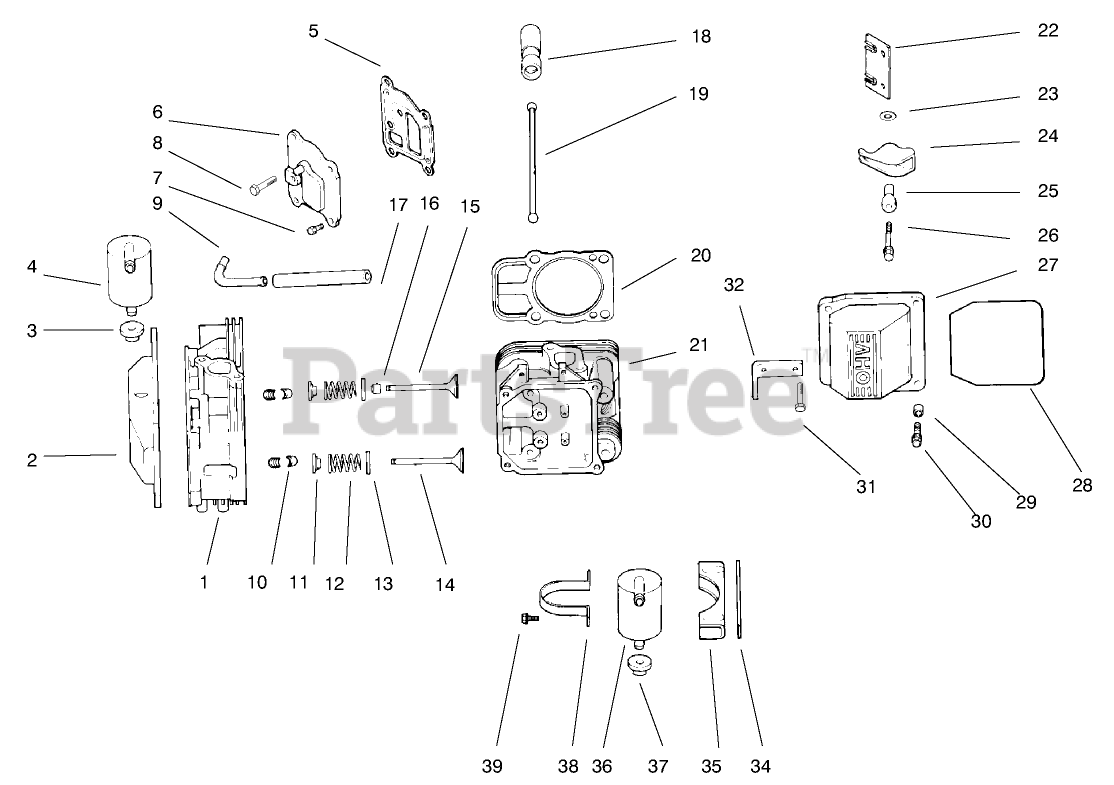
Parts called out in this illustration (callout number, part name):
1	#1 Cyl. Head Asm
2	Kit-Valve Incl 6 20-22
3	Grommet-Rubber
4	Kit-Breather INC 4
5	Gasket-Breather
6	Cover-Breather
7	Screw
8	Plug
9	Fitting
10	Retainer Kit
11	Cap-Spring, Valve
12	Spring-Valve
13	Retainer-Spring
14	Valve-Exhaust
14	Valve-Exhaust (.25)
15	Valve-Intake
15	Valve-Intake (.25)
16	Seal-Stem, Valve
17	Hose
18	Lifter-Valve
19	Rod-Push
20	Gasket-Cylinder Head
21	#2 Cyl. Head Asm,
22	Plate-Guide
23	Washer
24	Arm-Rocker
25	Pivot-Rocker Arm
26	Screw
27	Valve Kit
28	"O"Ring
29	Spacer
30	Screw
31	Screw
32	Strap-Lifting
33	Kit-Breather Incl 3-9
34	Spacer
35	Bracket
36	Separator-Oil Breather
37	Grommet
38	Strap-Lifting
39	Screw
